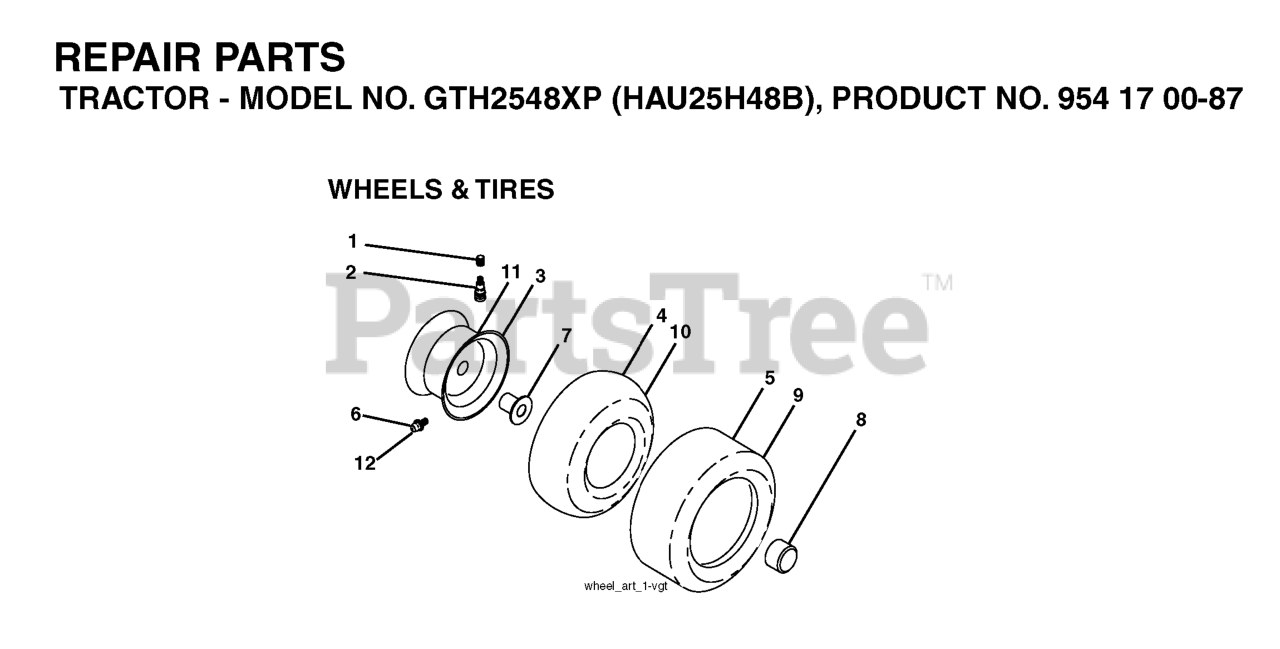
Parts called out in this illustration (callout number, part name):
2	VALVE STEM LT
3	RIM ASSEMBLY, FRONT
4	TUBE.16X6.5/7.5-8
5	TIRE HEAVY DUTY
6	FITTING LT
7	BEARING T
8	CAP, AXLE BLK
9	TIRE HEAVY DUTY
10	TUBE.23X9.5-12
11	RIM.ASM.12X7.REAR.SILVER
12	ZERK FITTING M
